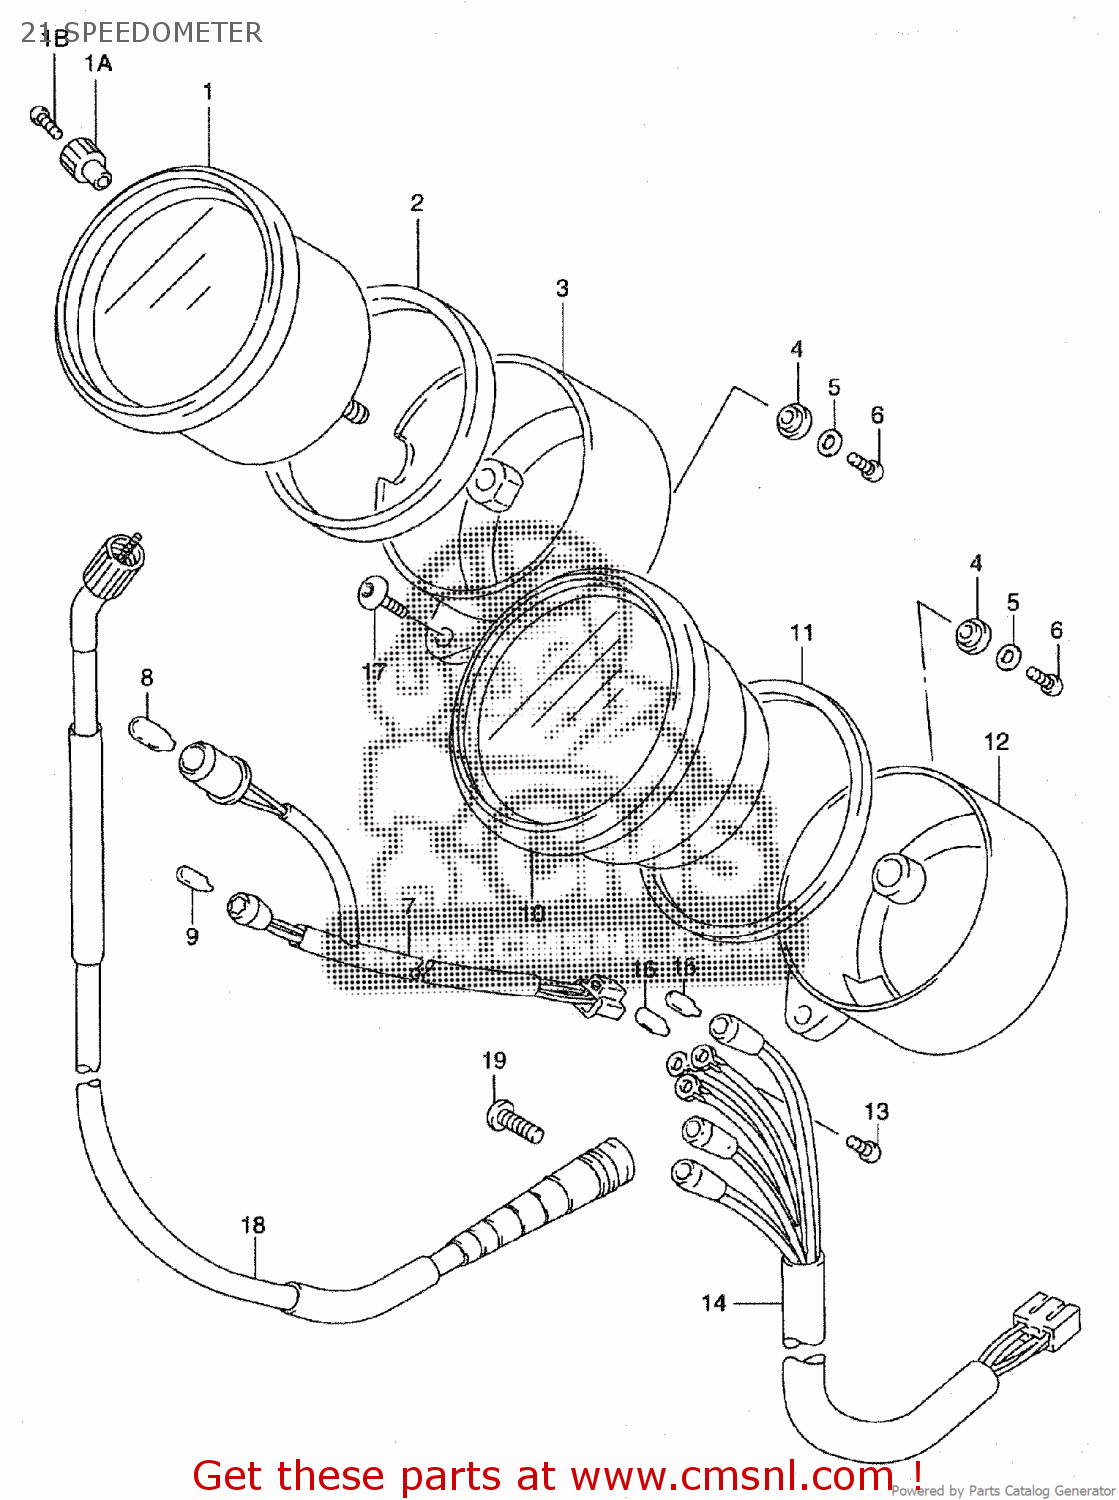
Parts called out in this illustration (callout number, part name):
1	SPEEDOMETER
1A	KNOB
1B	SCREW(2X6)
3	COVER
4	CUSHION,METER
5	WASHER
6	SCREW
8	BULB(12V1.7W,T10,WB121)
9	BULB(12V1.7W,T6.5)
10	TACHOMETER
12	COVER
15	BULB(14V1.4W,T5)
16	BULB(12V1.7W,T6.5)
17	SCREW(6X20)
18	CABLE ASSY,SPEEDOMETER
19	SCREW
